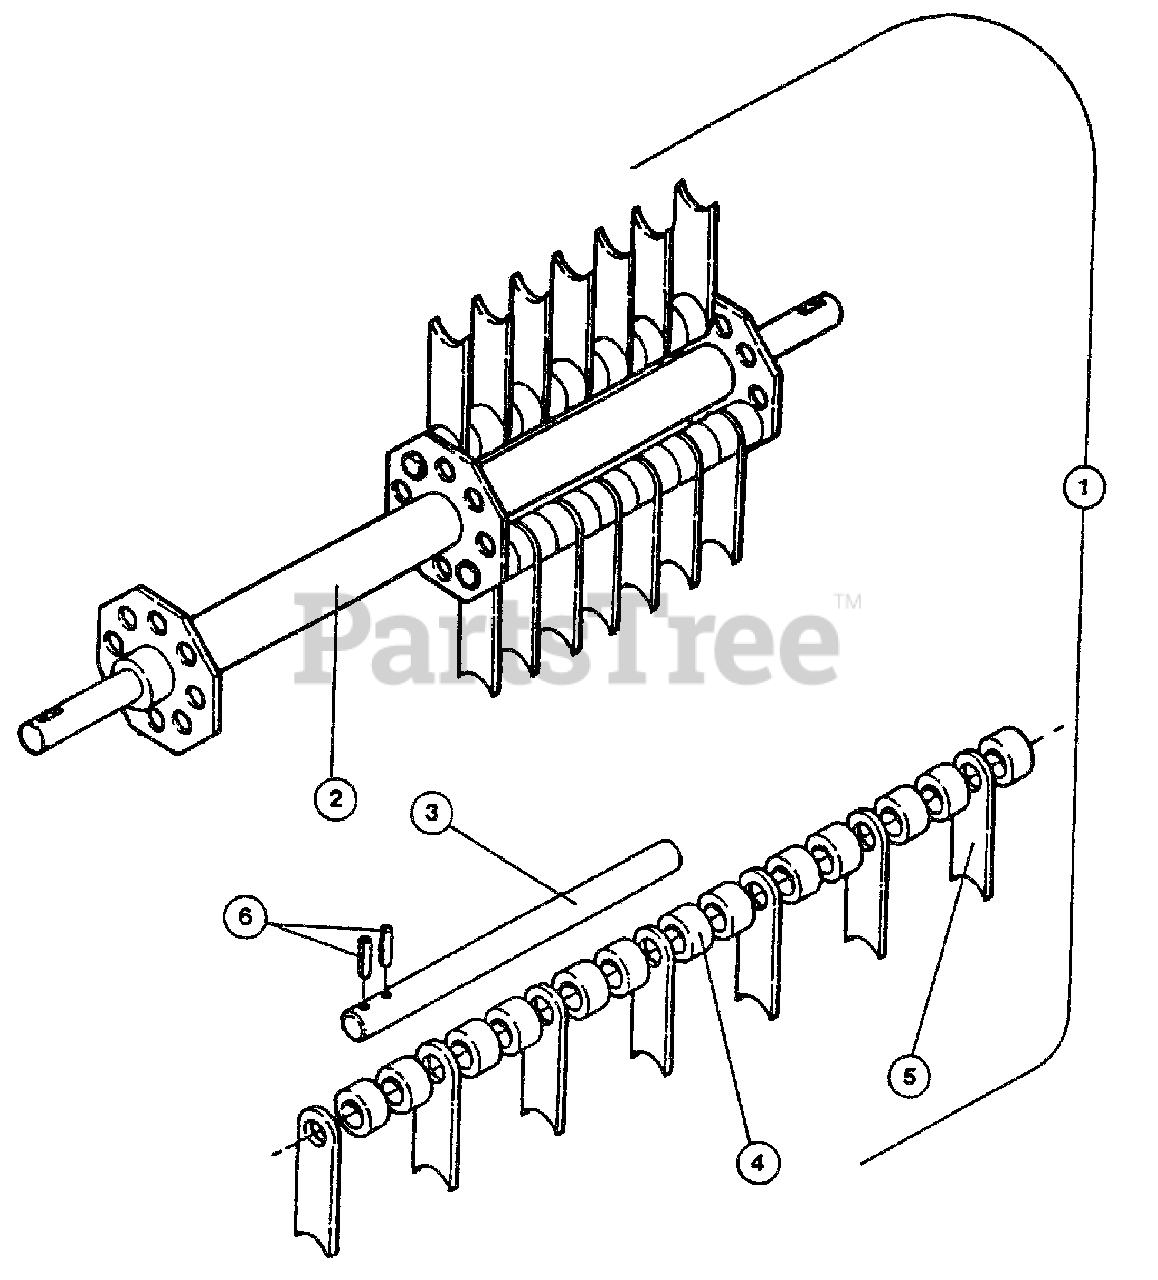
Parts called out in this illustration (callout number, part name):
1	Complete Dethatcher Shaft
2	Dethatcher Shaft, Bare
3	Satellite Shaft
6	1/8 x 7/8 Roll Pin
